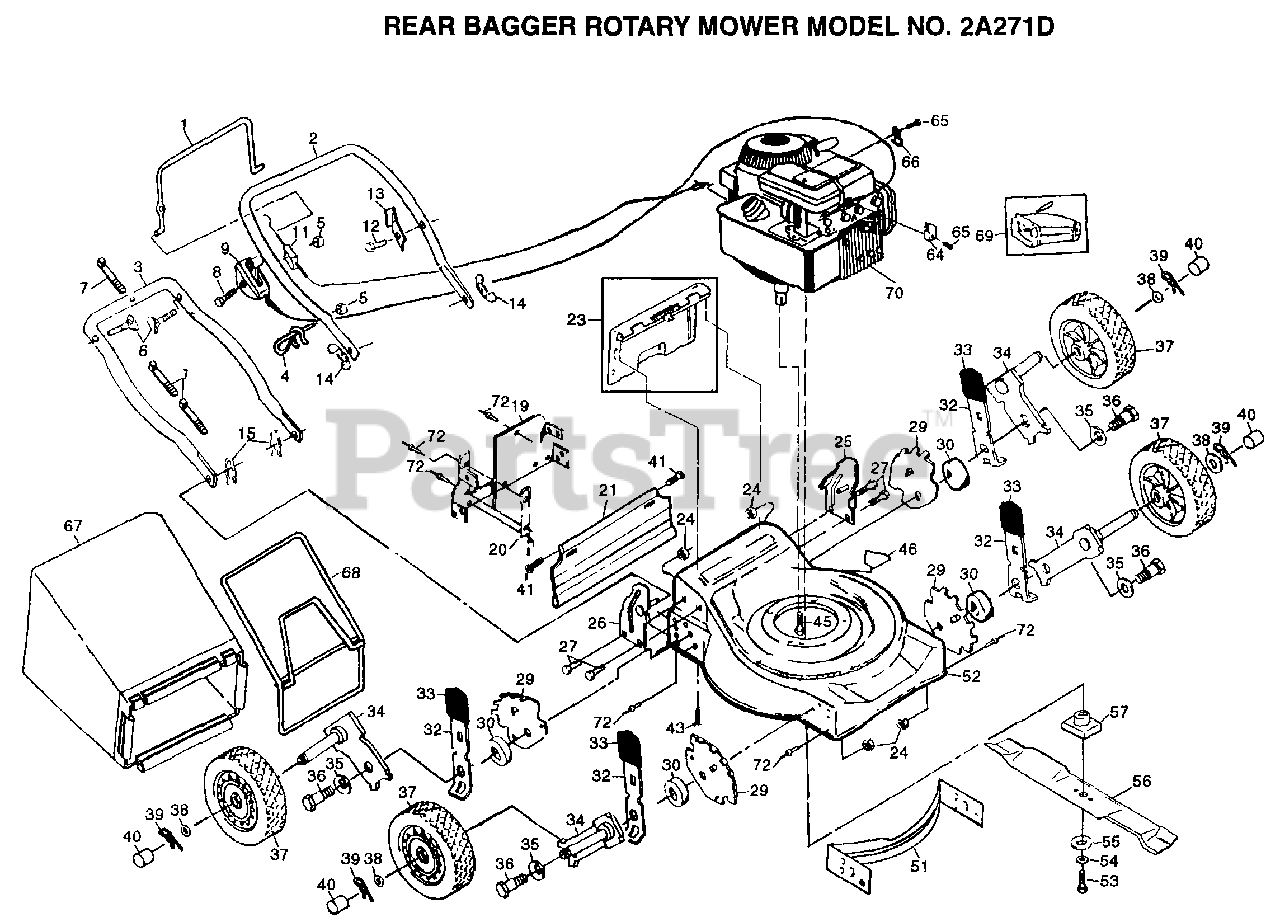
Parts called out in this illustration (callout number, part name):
1	CONTROL BAR
4	ROPE GUIDE
6	BOLT.HANDLE.LM
8	SCREW.HXHD.WASH.
9	CONTROL THROTTLE
11	"CABLE,ENG ZONE CO"
12	TAPPING SCREW
13	"BRKT,UPSTOP"
14	"NUT,WING PM"
15	HAIRPIN COTTER
19	PLATE.BACK.20RD
21	SKIRT.PUSH.20RD
23	KIT.DOOR.RR.20STL
24	LOCKNUT PM
27	SCREW
29	BRACKET.WHL.ADJ.9
32	SPRING SELECTOR
33	KNOB PM
34	AXLE ARM
35	"WASHER, BELLEVIL."
36	BOLT SHLD 3/8-16
37	WHEEL.ASM
38	WASHER
39	RETAINER CLIP PM
40	HUB CAP-PLASTIC
41	HINGE SCREW
43	SCREW
45	SCREW
46	DECAL HYT
53	SCREW
54	LOCKWASHER
55	"WASHER,HARDEN"
56	BLADE.20.MULCH.AY
57	BLADE ADAPTOR
64	CABLE CLAMP
65	SCREW PM
66	GUIDE CLIP PM
67	GRASS BAG
68	CATCHER FRAME
72	BLIND RIVET
